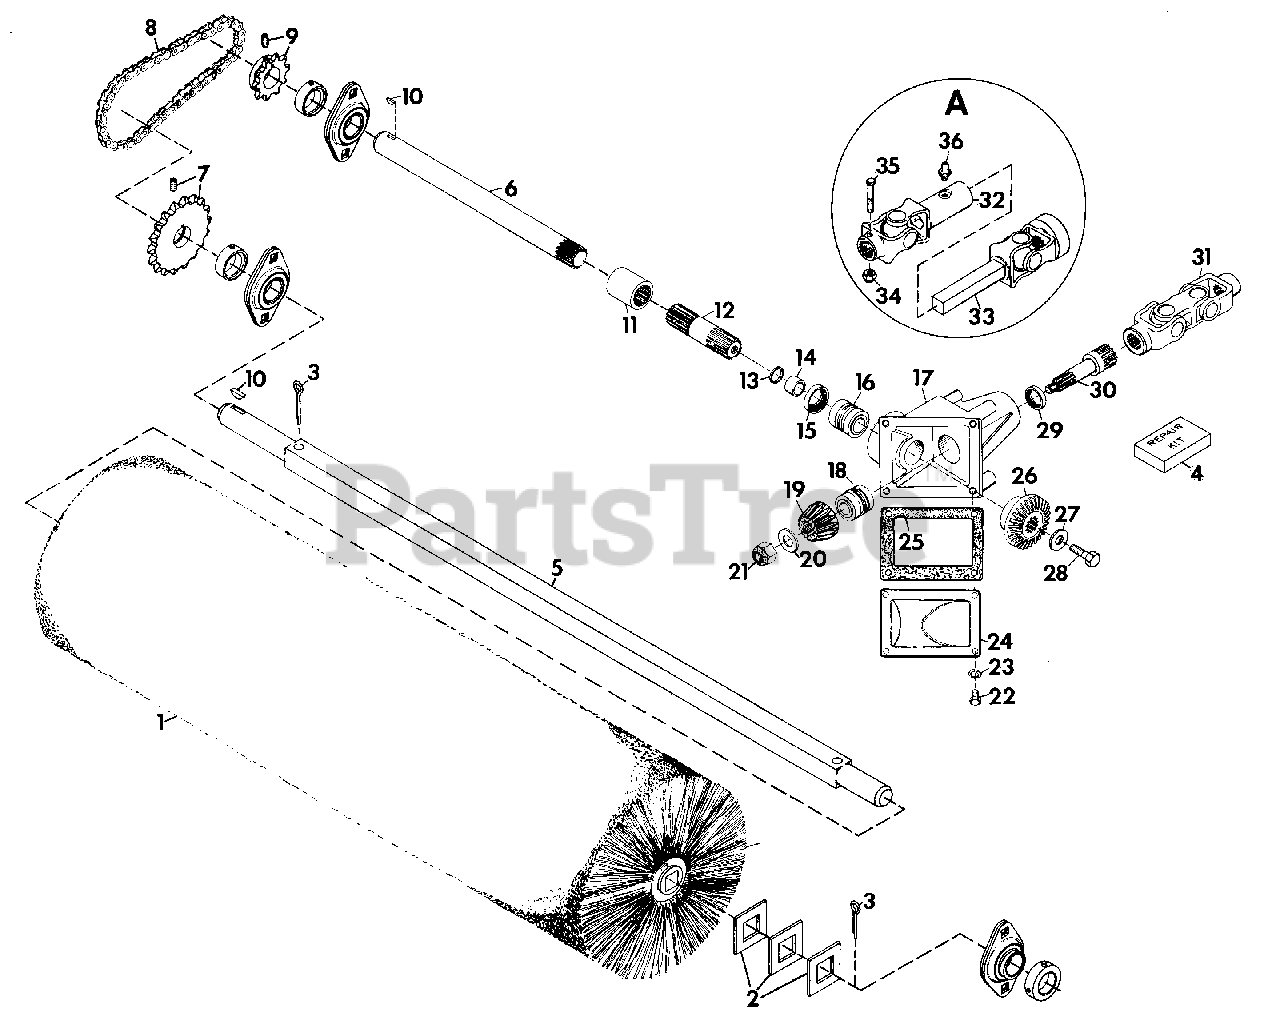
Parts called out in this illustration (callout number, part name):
1	BRUSH, 44 INCH
2	SPACER, SQUARE 1.010X2.000X.125
3	PIN, COTTER .250X2.000
4	KIT, REPAIR U-JOINT ROCKWELL STD.
4	KIT, REPAIR U-JOINT NEAPCO
5	SHAFT, POWER BRUSH
6	SHAFT
7	SPROCKET
8	CHAIN, ROLLER
9	SPROCKET
10	KEY, WOODRUFF .250X.750 HARD
11	COUPLING
12	SHAFT, DRIVE
13	RING, RETAINING 1.000 SHAFT
14	SPACER
15	SEAL, OIL 1.250X1.987X.250
16	ASSEMBLY, BEARING 1.00X1.98X1.243
17	CASTING, GEAR BOX
18	ASSEMBLY, BEARING .75X1.781X1.499
19	GEAR, BEVEL
20	WASHER, FLAT .531X1.000X.063
21	NUT, LOCK 1/2-20 LIGHT THIN
22	BOLT, HEX 1/4-20X.50
23	WASHER, LOCK 1/4 REG.
24	COVER, GEAR HOUSING
25	GASKET, GEAR HOUSING
26	GEAR, BEVEL
27	WASHER, .563X1.50X.180
28	BOLT, HEX 1/2-13X1 NYLON INSERT
29	SEAL, OIL 1.000X1.690X.250
30	SHAFT
31	ASSEMBLY, DOUBLE JOINT
32	U-JOINT, FEMALE END
33	JOINT, U MALE
34	NUT, LOCK 1/4-20
35	BOLT, HEX 1/4-20X2.00
36	FITTING, LUBE 1/4-28
